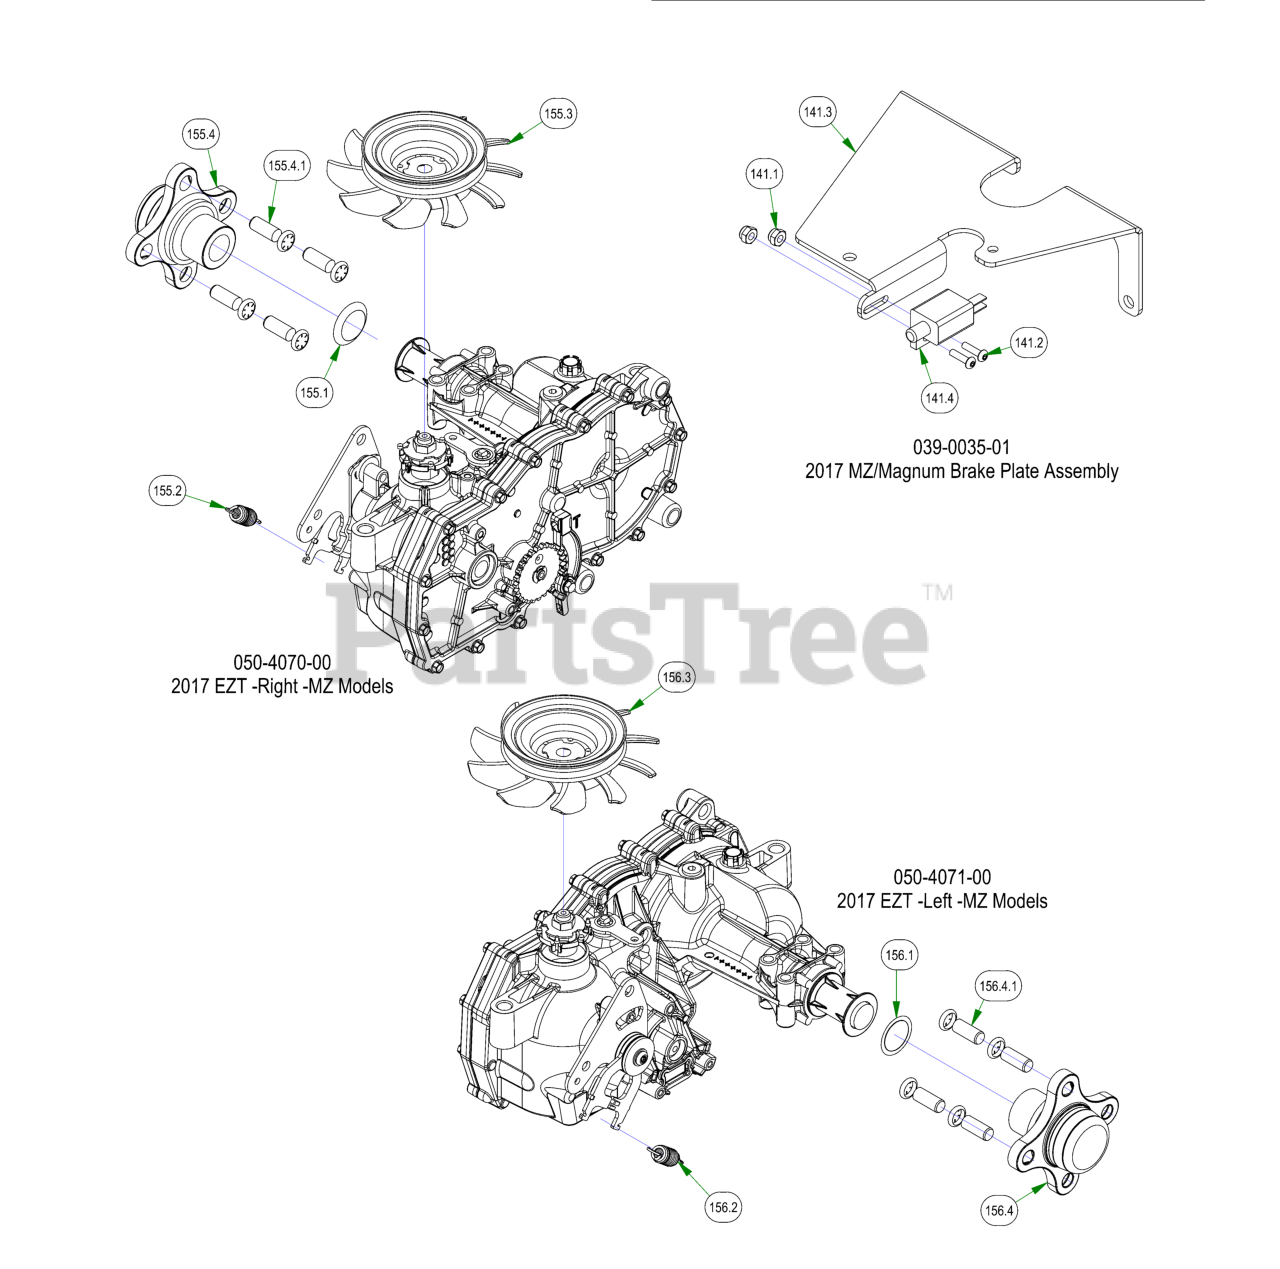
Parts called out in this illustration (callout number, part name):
141	2017 MZ/Magnum Brake Plate Assembly
141.1	#10 Nylock Nut
141.2	10-24 X 5/8 BS Button Head Bolt
141.3	2017 MZ Brake Lock Bracket
141.4	Safety Switch
155	2017 EZT -Right -MZ Models
155.1	MZ Seal & Retainer Kit
155.2	Gold Transaxle Spring
155.3	Fan/Pulley Kit for ZT / 2017 MZ
155.4	MZ 4 Bolt Hub Kit
155.4.1	Transaxle Wheel Studs/ Drum Brake Studs
156	2017 EZT -Left -MZ Models
156.1	MZ Seal & Retainer Kit
156.2	Gold Transaxle Spring
156.3	Fan/Pulley Kit for ZT / 2017 MZ
156.4	MZ 4 Bolt Hub Kit
156.4.1	Transaxle Wheel Studs/ Drum Brake Studs
